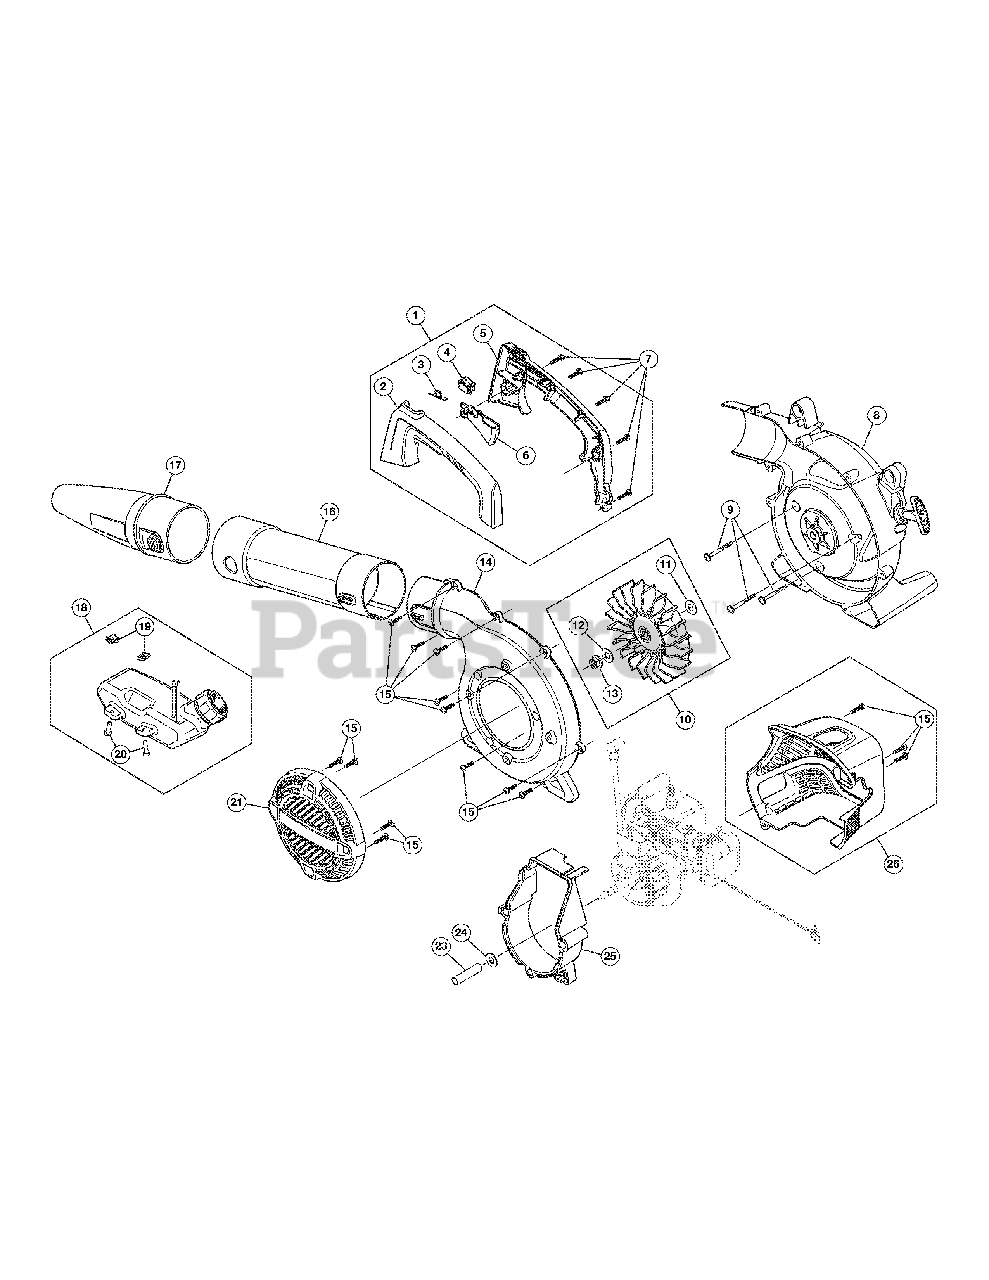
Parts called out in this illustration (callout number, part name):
1	Handle Assembly
2	Handle (LH)
3	Trigger Spring
4	On/Off Switch
5	Handle (RH)
6	Throttle Trigger
8	Impeller Housing Assembly (RH)
10	Impeller Assembly
11	Washer
12	Lock Washer
14	Impeller Housing Assembly (LH) (Incl.15)
16	Upper Blower Tube
17	Blower Nozzle
18	Fuel Tank Assembly
19	U-Shaped Nut
21	Intake Cover (Incl. 15)
23	Shaft Spacer
24	Washer
25	Engine Adapter (Incl. 9)
26	Engine Cover Housing (Incl. 15)
